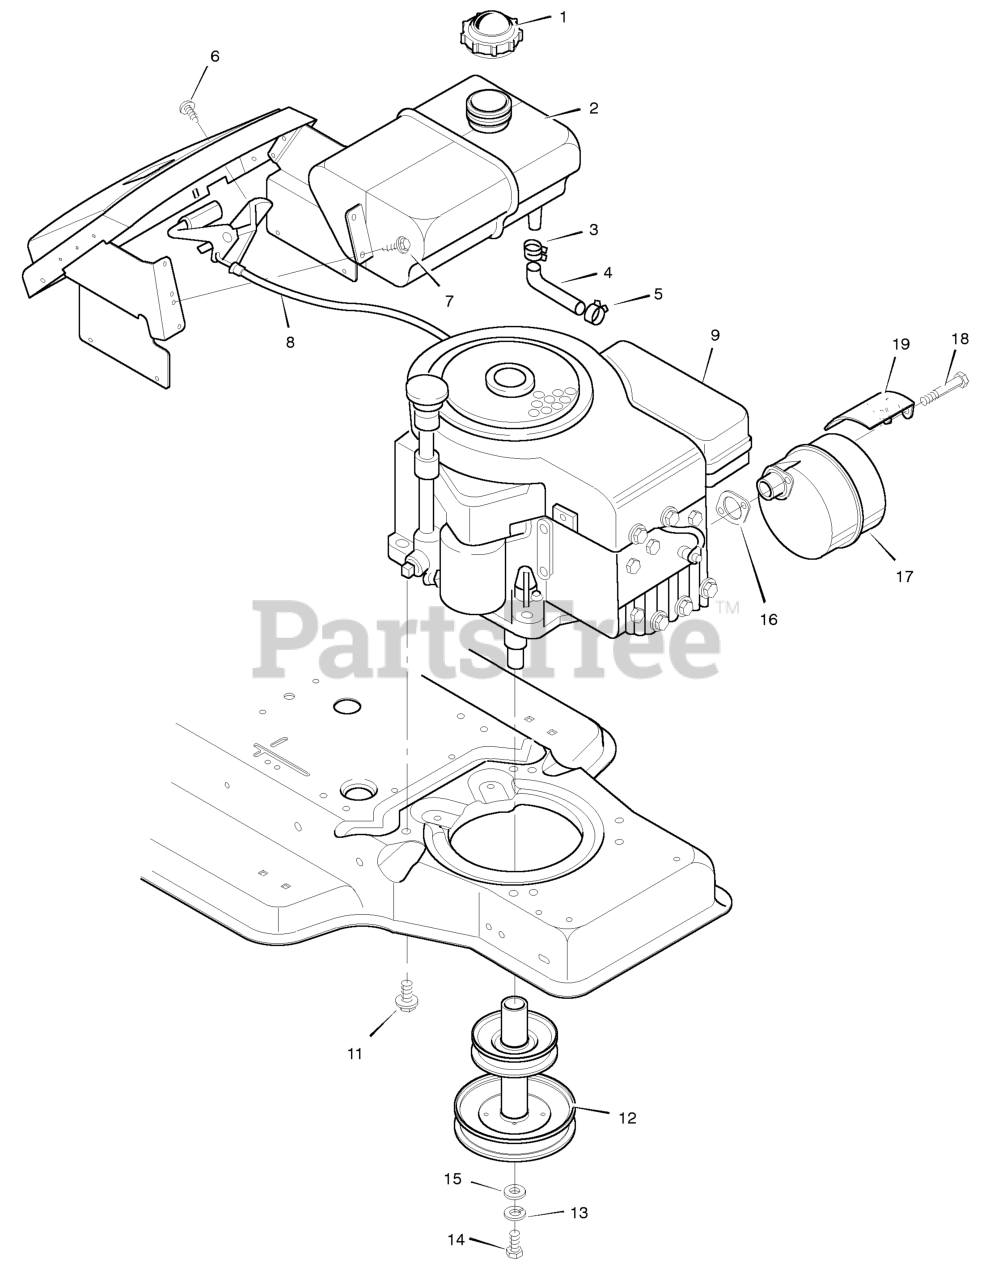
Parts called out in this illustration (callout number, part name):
1	Fuel Cap
2	Fuel Tank
3	Hose Clamp
4	Fuel Line
5	Hose Clamp
8	Throttle Control
9	Engine *
11	Bolt, Engine Mount
12	Stack Pulley Assembly
13	Lockwasher
14	Bolt, Hex
16	GASKET, Exhaust
18	Bolt, Hex
19	Shield, Heat
